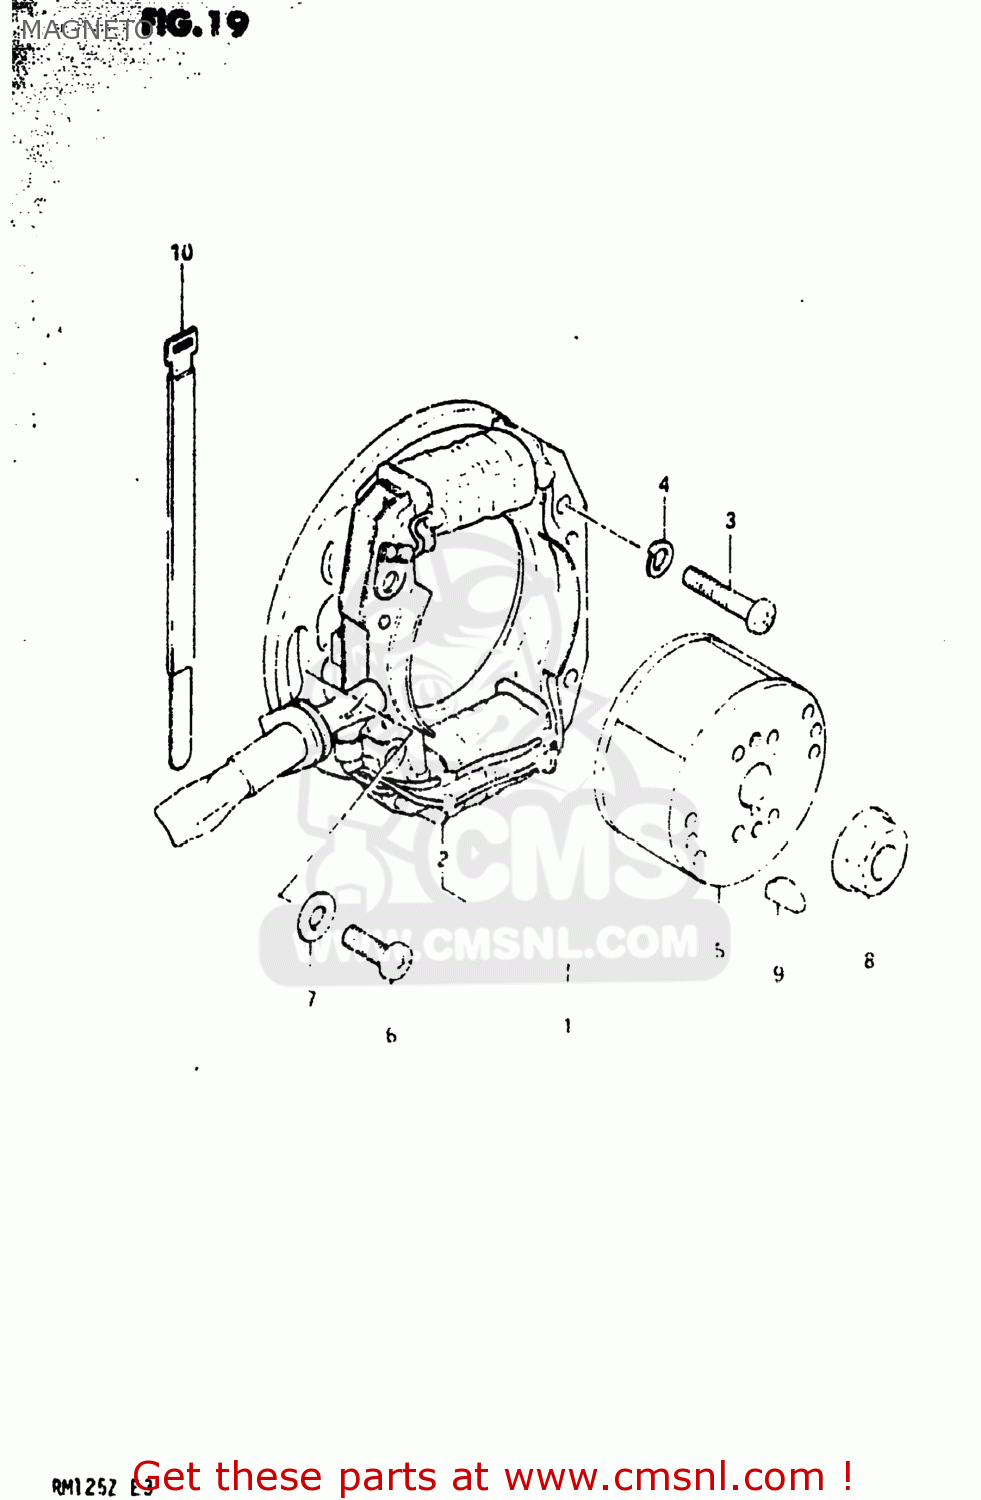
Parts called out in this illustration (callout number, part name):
1	MAGNETO ASSEMBLY
2	STARTER ASSY
3	SCREW 5X20
4	LOCK WASHER
5	ROTOR ASSEMBLY
6	SCREW
7	WASHER
8	NUT
9	KEY 4MM
10	CLAMP
